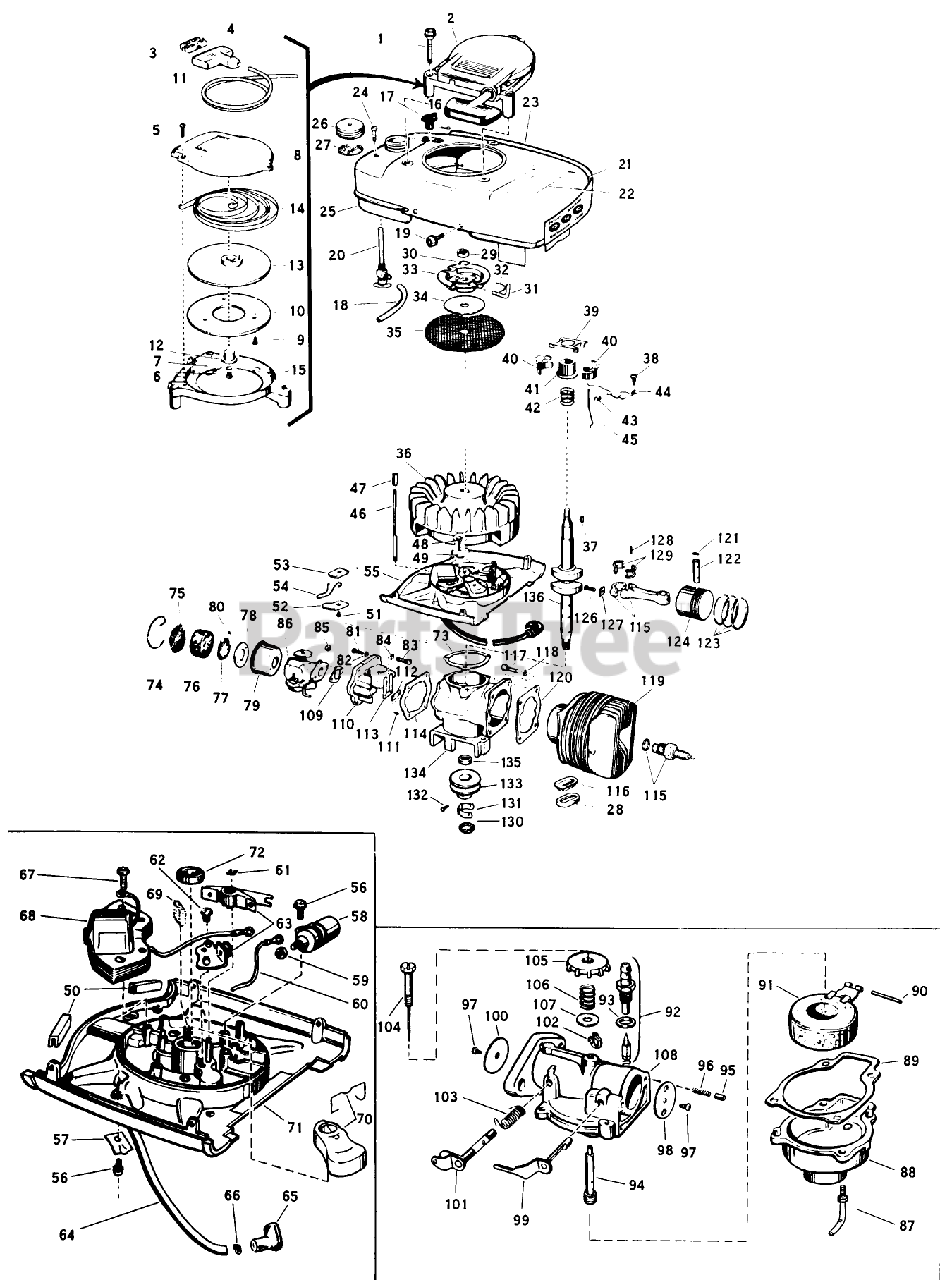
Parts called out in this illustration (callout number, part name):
10	Plate-Pulley
14	RECOIL SPRING
16	Cotter Pin-Choke Knob
17	KNOB, CHOKE BAR
19	SCREW S
20	VALVE&SCREEN SM
22	Decal-Instruction
26	Gas Cap
31	PIN - STARTER
41	COLLAR S
43	WEAR BLOCK S
44	GOVERNER LEVER AY
45	GOVERNOR ROD S
51	Screw Shut-off Switch
63	BREAKER AY. S
65	Cover-Rubber
73	GASKET S
76	ELEMENT
78	BACK-UP PLATE
81	SCREW S
85	STOP NUT
97	Screw-Choke Disc
99	CHOKE SHAFT&LVR AY
103	SPRING
104	NEEDLE AY. S
106	Spring-Ndl. Adj.
109	GASKET S
112	PLATE-BACKUP, REED
115	Spark Plug Gasket
121	RING-RETAINING
129	LINER ASM
